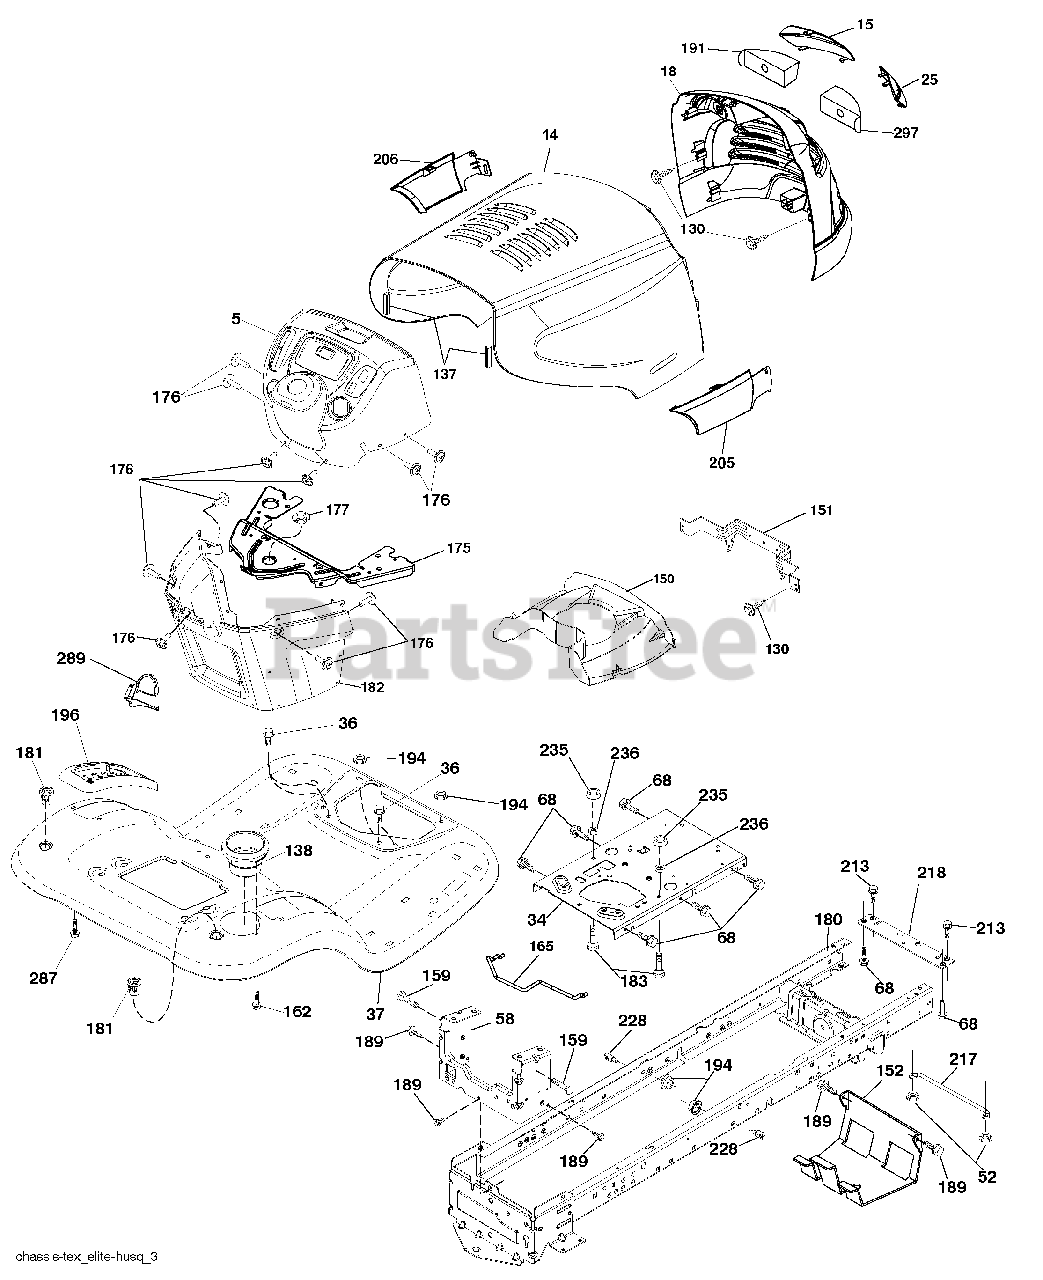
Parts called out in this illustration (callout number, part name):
5	Dash upper tex elite el ck 428
14	Hood pnt elite spl-tp w-skirts
15	lens elite-husq clear LH
18	Grille asm elite dl BLK
25	Lens elite-husq clear RH
34	Plate engine welded chassis
36	Screw 5/16-18 x 3/4 smgml tap/r
37	Fender tlt w/cph w/fw 421
52	Nut, hex, crownlock 5/16-18
58	Drawbar upper 2pc sml fender
68	Screw thdrol 5/16-18 x 1/2tytt
130	Screw
137	Bumper hood large 1 75"
138	Cupholder tl tex 428
150	Air duct
151	Bracket pivot lasr/elte/husqlt
152	Shield browning w/tex
162	Screw hex wsh hi-lo 1/4 x 1/2 unc
175	Crossmember lt
176	Screw #10-24x5/8 rnd qudrx gim
177	Bushing steering yt/gt
180	Chass wldmt tl 12 ga/2pc 18/22"
181	Bushing mnt fend crgo blk tex
182	Dash lower lt ccs
183	Bolt fin hex 5/16-18 unc x 1-1/4
189	Screw 5/16-18 x 3/4 smgml tap/bl
191	Insert lens rflct elt-husq
194	Nut, lock hex flange 5/16-18 unc
196	Console asm decklft bl/rbt tlt
205	Skirt side rh elite husq 428
206	Skirt side lh elite husq 428
213	Bolt, hex head 5/16-18 x 3/4
217	Rod pivot hood
218	X-piece hood stop non/stealth
228	Stud fastner w/'d'anti-rotatio
235	Spacer fender
236	Nut center lock 5/16-18 unc
287	Screw hex washead 1/4-20 x 3/8
289	Plug cruise hook phone
297	Insert reflective RH
